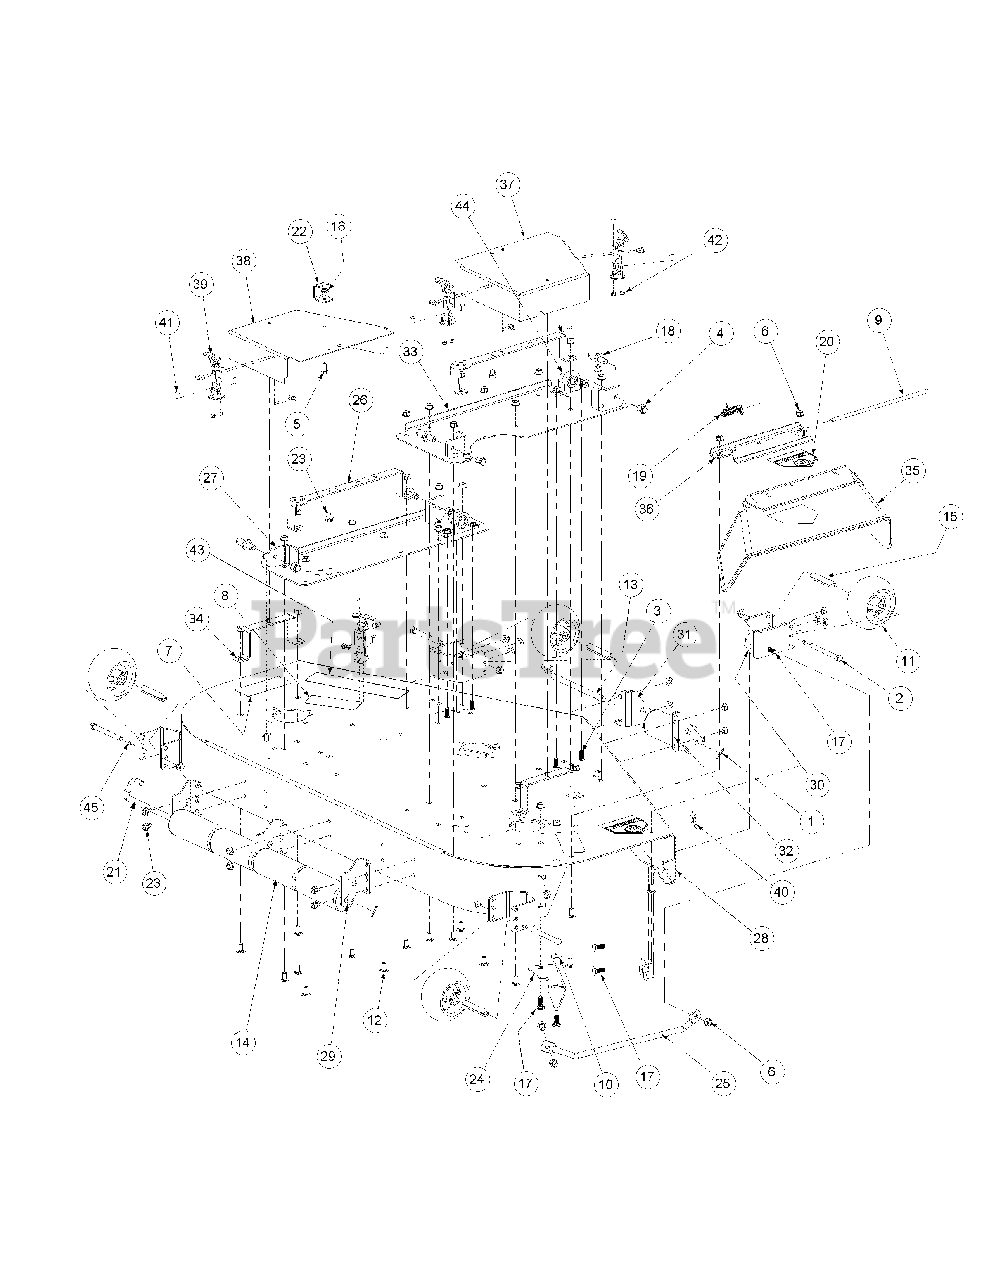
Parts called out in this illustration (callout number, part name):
1	Cotter Pin, .125 Dia x 1.0
2	Hex Cap Screw, 3/8-16, 3.75
3	Carriage Screw, 3/8-16 x 1.25
4	Lock Nut, Nylon Insert, 1/2-13
5	Hex Cap Screw, 5/16-18 x 3/4
6	Hex Nut, 3/8-16 Flange Lock
7	Decal Rotating Blade
8	Decal, Warning Shield Missing
9	Defllector Chute Rod
10	Idler Washer
11	Complete Wheel, 5.00 Dia.
12	Carriage Bolt, 3/8-16 x .75 Lg.
13	Roller Pin. 1/2 Dia. x 7.31 Lg.
14	Front Roller
15	Wheel Spacer
16	Hexflange Lock Nut, 5/16-18
17	Carriage Bolt, 3/8-16 x 1
18	Pin, 5/8 Dia. x 1.2 Lg.
19	Spring Torsion, 0.4 ID x 2.16 LG
20	Decal, Danger Hands and Feet
21	Roller Pin
22	Tension Rod Stop Bracket
23	Hex Index Washer Screw, 3/8-16, .5
24	Chute Bracket
25	Finger Guard
26	Cover Support
27	Left Hand Mount, Deck Bracket Assembly
28	54 Deck Assembly
29	Roller Mount Bracket
30	Anti-Scalp Wheel, Front Mount Bracket
33	Deck Bracket Assembly
34	Outer Belt Cover Support Assembly
35	Deflector Chute
36	Deflector Chute Bracket
37	Right Hand Belt Deck Cover
38	Left Hand Belt Deck Cover
39	T-Handle Draw Latch
40	Decal, 54"
41	Phillips Head Screw, 10-32
42	Lock Nut, Nylon Insert, 10-32
43	Mower Deck Label
44	Pillow Block
45	Flat Washer, 3/8
